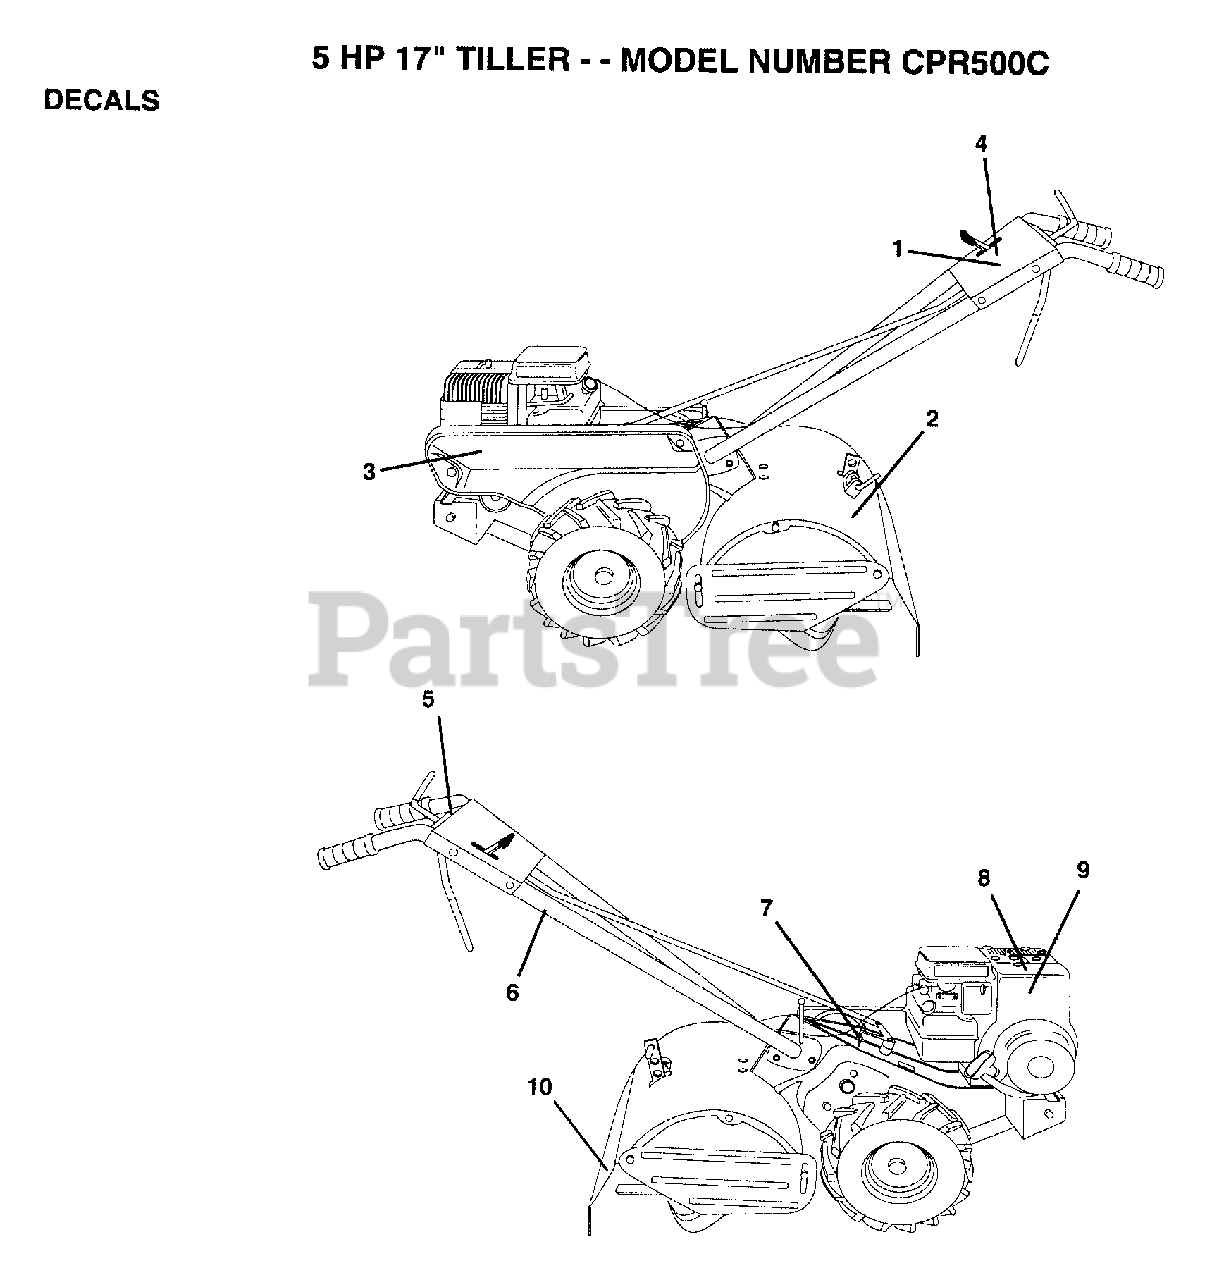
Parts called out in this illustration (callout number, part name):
1	DECAL, PANEL CONTROL
2	DECAL, LOGO
3	DECAL, LOGO
4	DECAL, LOGO
6	DECAL TI
7	DECAL CRT
10	DECAL TI
